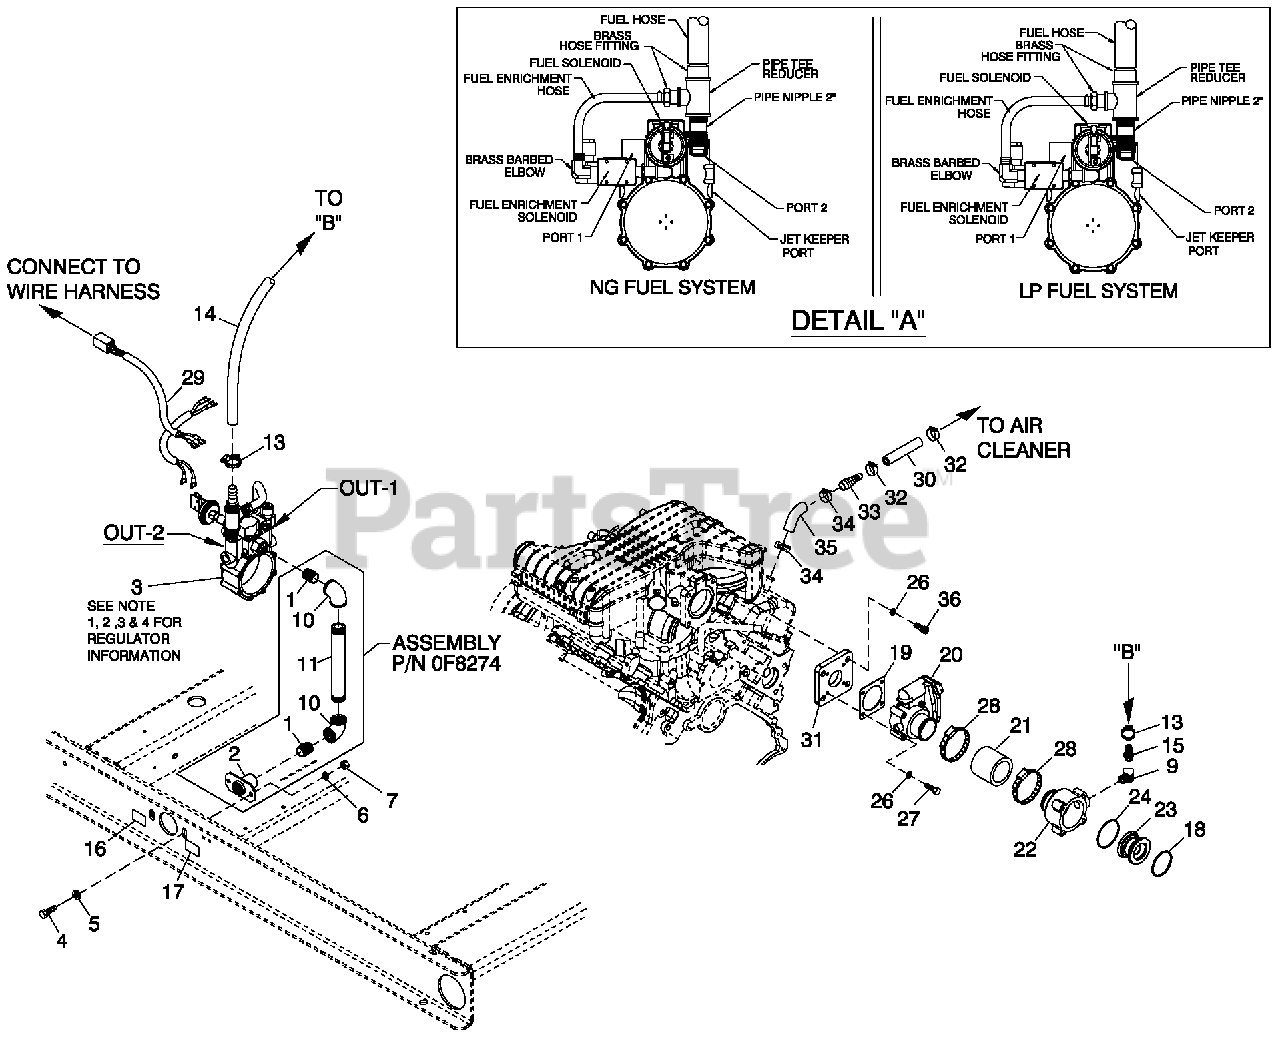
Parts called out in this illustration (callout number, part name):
1	NIPPLE CLOSE 3/4X1.375
2	FLANGE FUELINLET
3	REGULATOR ASSY 4.2L 48KW
4	SCREWH HCM8-1.25X20 G8.8
5	WASHER FLAT 5/16-M8 ZNC
6	WASER LOCK M8-5/16
7	NUT EX M8-1.25 G8 CLEARZINC
9	STREETEL 45D1/2NPTBRASS
10	ELBOW 90D 3/4 NPT
11	NIPPLEPIPE 3/4 NPT X 7
13	CLAMP HOSE #10 .56-1.06
14	HOSE 3/4 ID SAE-30R2 (22" LG)
15	BARBEDSTR1/2 NPTXi3/4
16	DECAL INLETPRESSURE
17	DECAL FUEL INLETNG(NATURAL GAS APPLICATION)
18	O-RING 45.63 IDX2.62 WIDT
19	GASKET BOSC 32
20	ACTUATORBOSC 40 GOVERNOR
21	HOSE COOL 2 IN ID 20R4
22	MIXER ACTUATOR 40MM MAC INED
23	VENTURIT HROTTLE 26MM
24	O-RING 47.625 IDX2.38 WIDT
26	WAS ERLOCKM6-1/4
27	SCREW SC M6-1.0 X 45 G12.9
28	CLAMPOSE #28 1.32-2.25
29	HARNESS CPL FUEL JUMPER
30	HOSE 3/8 DSNGLE BRAD (20" LG)
31	NTAKE ADAPTER 4.2L G3-BOSC
32	CLAMP OSE BAND .63
33	HOSE BARB REDUCER 5/8"-3/8"ID
34	CLAMP HOSE BAND .88"
35	HOSE COOL 5/8"ID 250&WP (2" LG)
36	SCREWS CM6-1.0X18 G12.9
